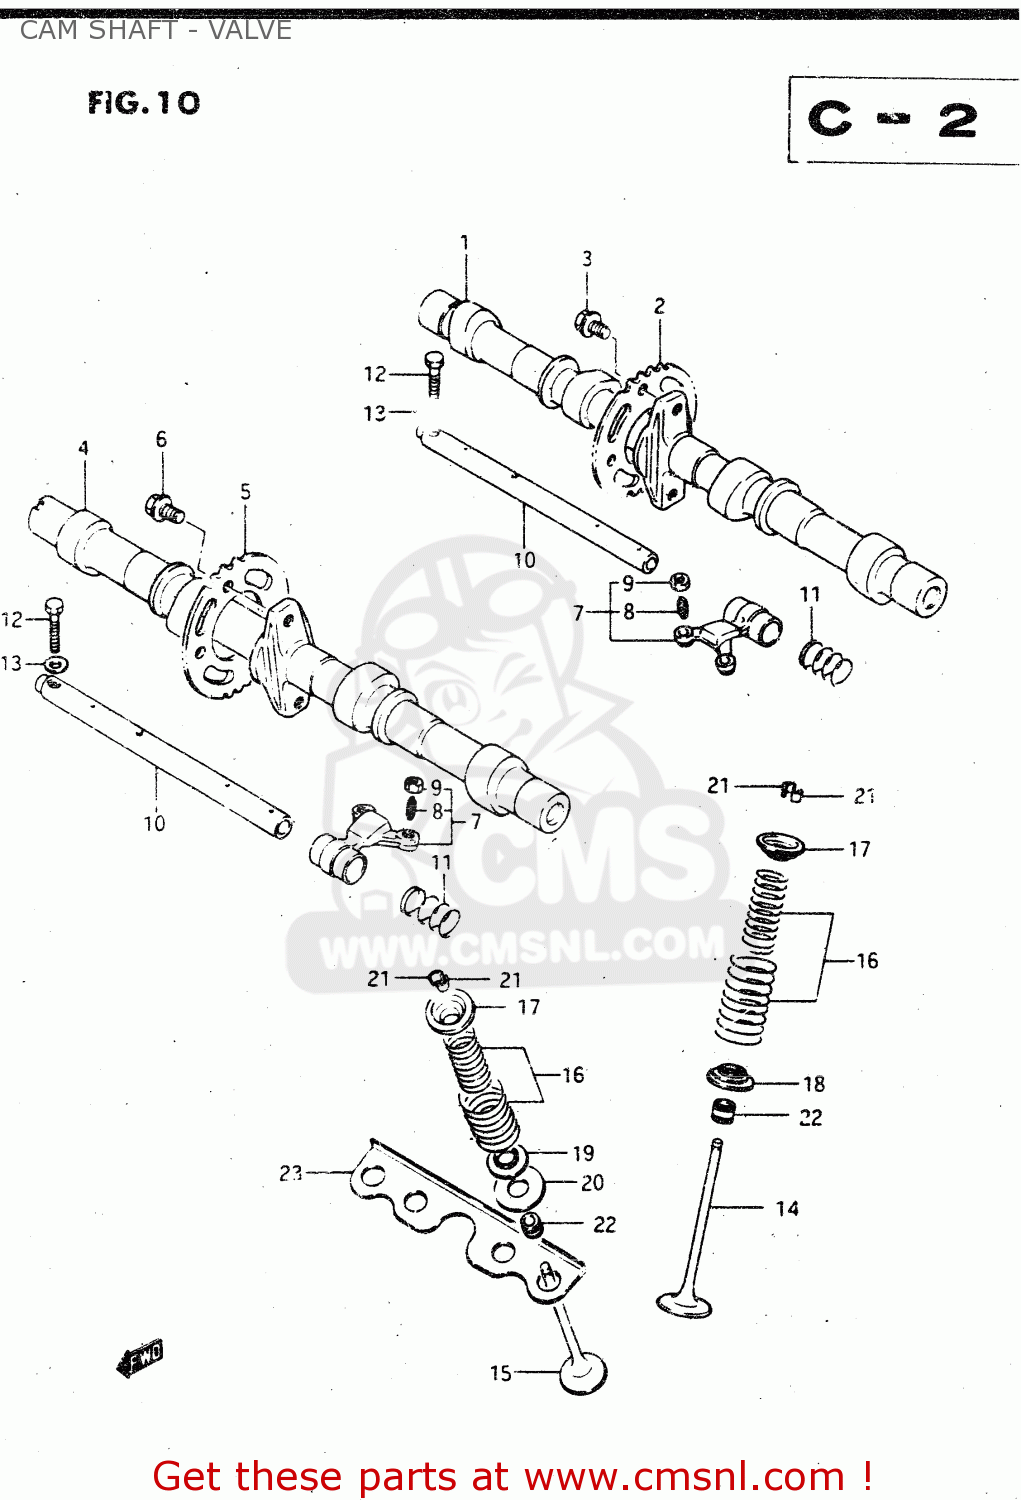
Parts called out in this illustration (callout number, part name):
1	CAMSHAFT
2	SPROCKET,CAMSHAFT
3	BOLT(7X11)
4	CAMSHAFT,EXHAUST
5	SPROCKET,CAMSHAFT
6	BOLT(7X11)
7	ARM,VALVE ROCKER
8	SCREW,TAPPET ADJUSTING
9	NUT,TAPPET ADJUSTING
10	SHAFT,VALVE ROCKER ARM
11	SPRING
12	BOLT
13	WASHER, LOWER
14	VALVE,INTAKE
15	VALVE,EXHAUST
16	SPRING SET,VALVE
17	RETAINER,VALVE SPRING
18	SEAT,VALVE SPRING
19	SEAT,VALVE SPRING
20	SEAT,VALVE SPRING EXH OUTER
21	COTTER VALVE
22	OIL SEAL
23	PLATE
